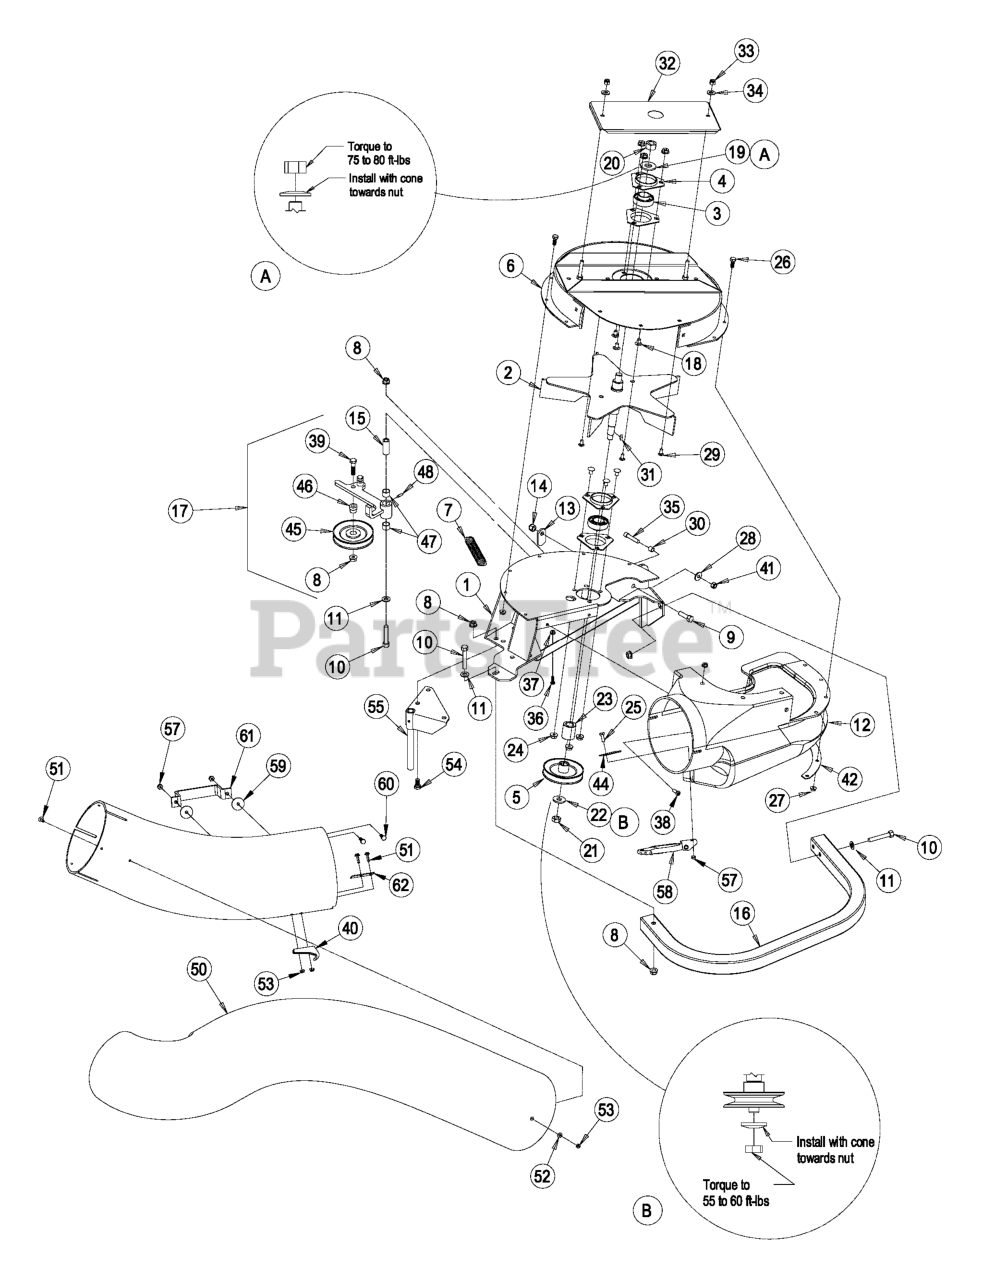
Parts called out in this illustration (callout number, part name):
2	IMPELLER
3	BEARING
4	HOUSING-FLANGE
5	SHEAVE
6	ASM, UPPER HSG
7	SPRING-IDLER
8	NUT-HHF, WHIZ
9	SCREW-HH
10	SCREW-HH
11	WASHER-FLAT
12	CHUTE, BLOWER
13	LATCH-CATCHER, GRASS
14	NUT-LOCK, NI
15	BUSHING
17	ASM, IDLER ARM - SERVICE
18	SCREW-CARR
19	WASHER-SPRING
20	NUT-HEX
21	NUT-JAM
22	WASHER-SPRING
25	SCREW-HH
26	SCREW-HH
28	WASHER-SPRING
29	SCREW-CARR
30	BUSHING, LOCATOR
31	KEY-WOODRUFF
32	ASM, BEARING COVER
33	NUT-LOCK, NI
34	WASHER-FLAT
35	SCREW-HSH
36	SCREW-HEAD, TRUSS
39	SCREW-HH
40	LATCH-CATCH
41	NUT-HEX
42	PLATE-BACKING, BLOWER
44	PLATE-BACKING
46	HUB,SPACER
47	BUSHING
48	FITTING-GREASE
51	SCREW-HWH
52	WASHER-FLAT
53	NUT-LOCK, NI
54	SCREW-HH
55	PIN-MOUNT
57	NUT-LOCK, NI
58	LATCH-RUBBER
59	WASHER-FLAT
60	SCREW-HH
62	PLATE-BACKING
